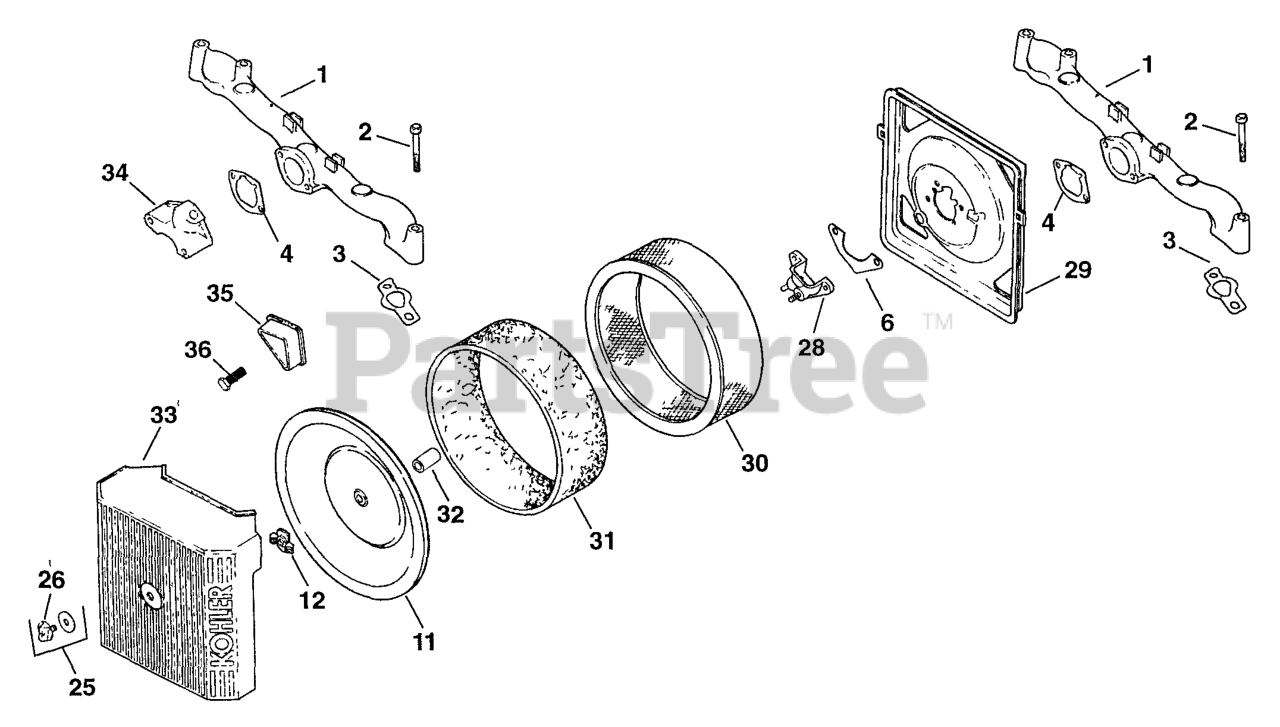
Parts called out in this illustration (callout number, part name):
1	MANIFOLD, INTAKE
2	Screw, hex. flange M6x1.0x55
3	GASKET, INTAKE MANIFOLD USE 24 041 79-S
4	GASKET, AIR CLEANER BASE
34	ELBOW, AIR CLEANER - DISC.
35	COVER, BLOWER HOUSING USE 24 096 160-S
36	SCREW, WSH HD TAP #8-18X1/2" USE 25 086 91-S
